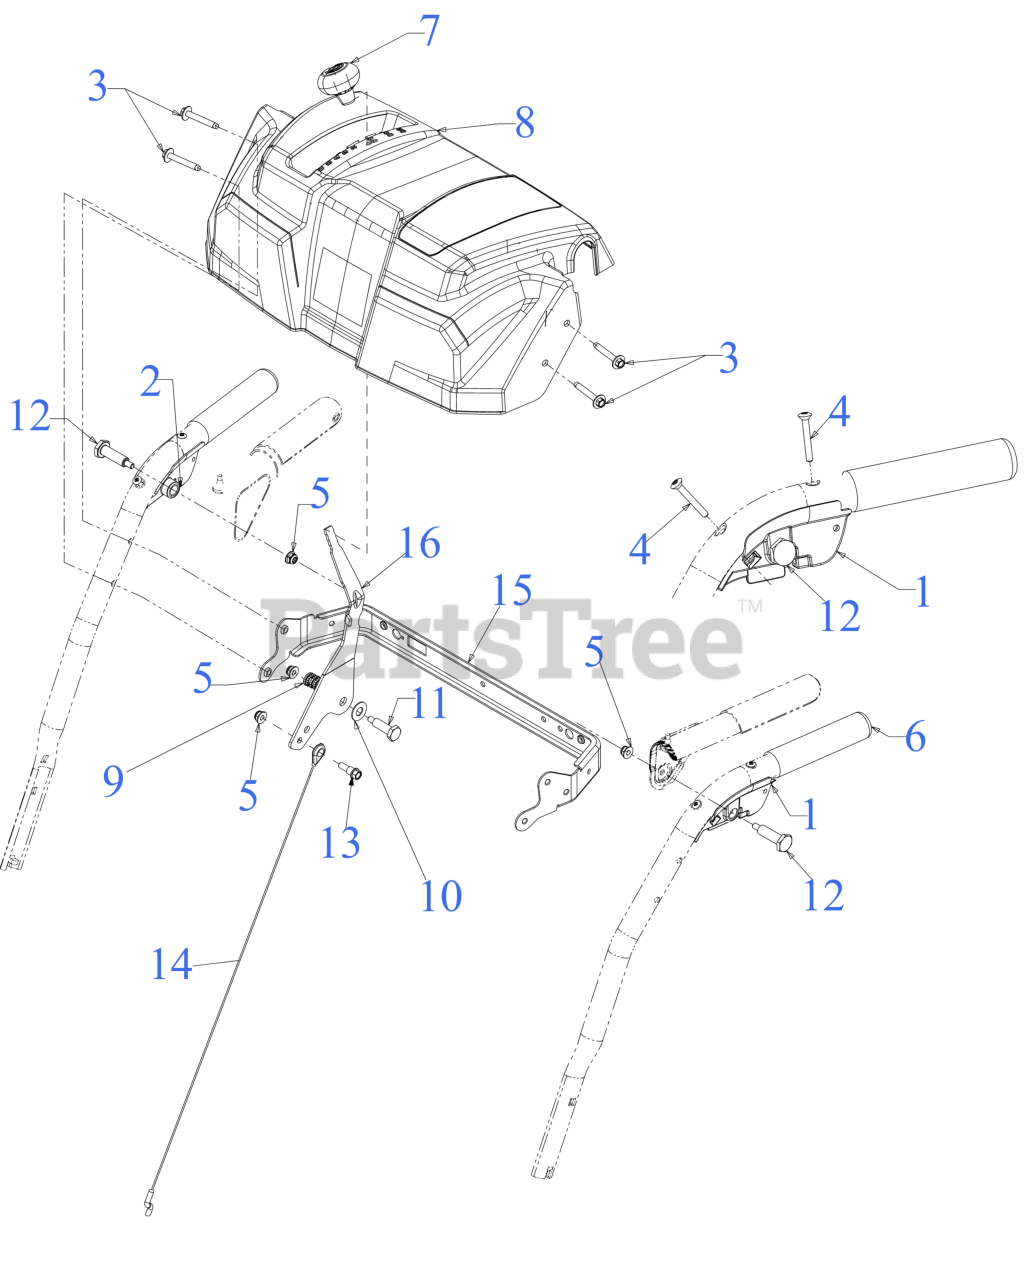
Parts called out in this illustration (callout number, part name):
1	CLUTCH LOCK HANDLE ASSEMBLY (LH)
2	CLUTCH LOCK HANDLE ASSEMBLY (RH)
3	SCREW 1/4-20 x 1.625
4	SCREW #10-24 x 1.375
5	FLANGE LOCK NUT
7	SHIFT KNOB
8	HANDLE PANEL (TROY-BILT)
9	COMPRESSION SPRING
10	FLAT WASHER .401X.88
11	SHOULDER SCREW
12	SHOULDER SCREW .437 x 1.345 1/4-20
13	SHOULDER SCREW .342X.335X1/4-20
14	SELECTION CABLE
